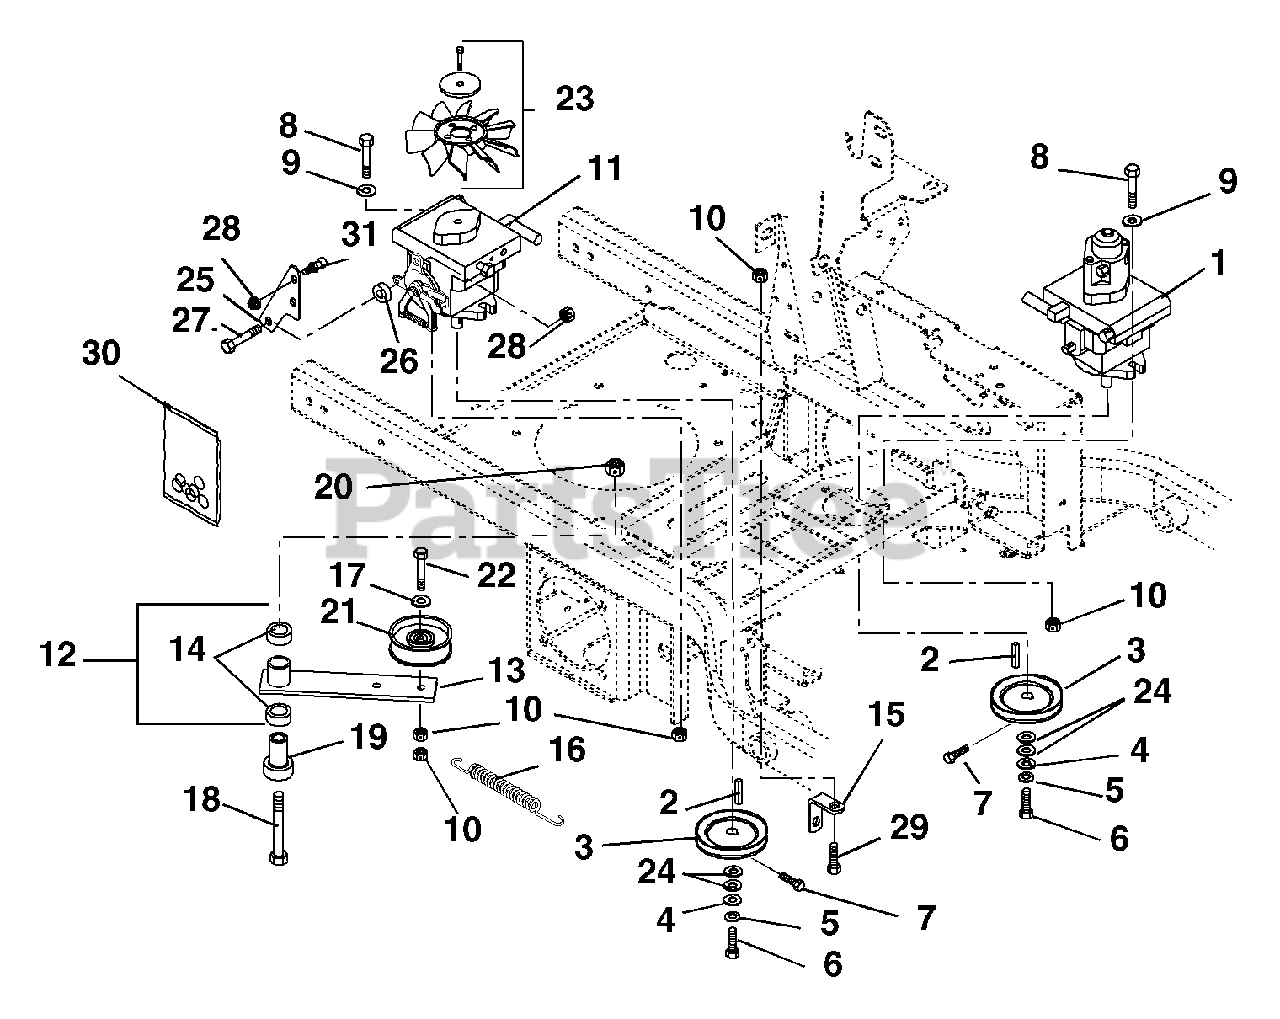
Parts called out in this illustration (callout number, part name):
1	Hydrostat BDP with Auxiliary
2	Key, Straight 5mm x 25mm x 5mm
3	Sheave 4.0 x .199
4	Washer, Flat Steel .281 x 1.00 x .063
5	Washer, Locking .25 x .062
6	Bolt, Hex M6 x 1.0 x 12
7	Bolt, Hex .25-20 x .50 Grade 5
8	Bolt, Hex .38-16 x 1.25 Grade 5
9	Washer, Flat Steel .39 x .75 x .125
10	Nut, Locking Top Flange .38-16
12	Assembly,Idler Arm Guard Drive
13	Weldment, Idler Arm Ground Drive
14	Bearing, 1.00 x 1.12 x .75
15	Anchor, Idler Spring
16	Spring, Tension .120 x .845 x 6.50
17	Washer, Flat Steel .39 x.75 x.125
18	Bolt, Hex .50-13 x 3.50 Grade 5
19	Bearing, Pedestal Powdered Metal
20	Nut, Locking Top Flange .50-13
21	Idler, Flat 4.00 x 1.06
22	Bolt, Hex .38-16 x 2.25 Grade 5
23	Fan, Cooling
24	Washer, Flat Steel .656 x 1.31 x .095
25	Bracket, Return to Neutral/Damper
26	Spacer .344 x 1.00 x .375
27	Bolt, Hex .31-18 x 1.25 Grade 5
28	Nut, Locking Top Flange .31-18
29	Bolt, Hex .38-16 x .75 Grade 5
30	Kit, Pump Seal (BDP-10A)
31	Stud, Ball
